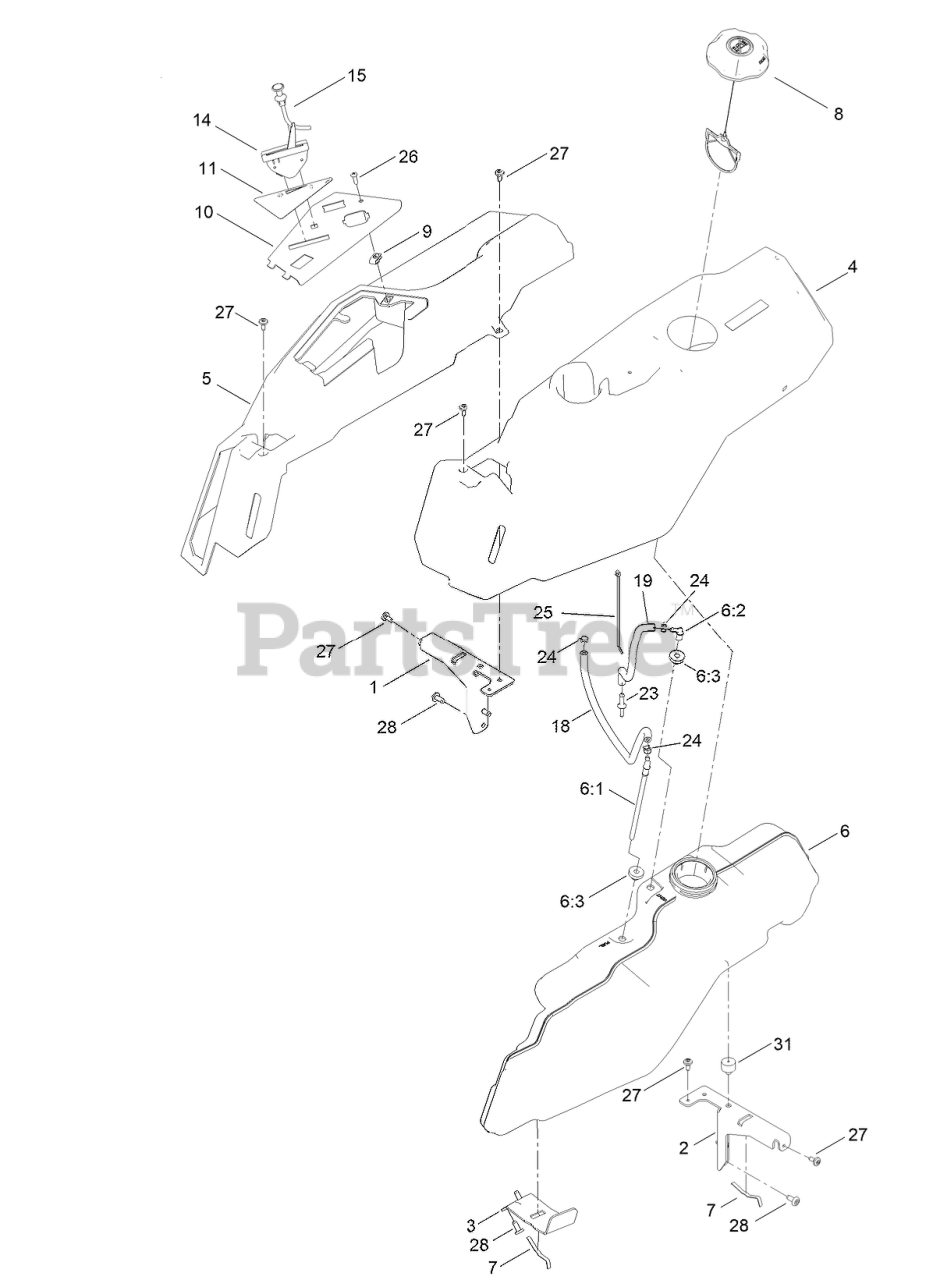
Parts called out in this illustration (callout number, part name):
1	SUPPORT-POD, RH
2	SUPPORT-POD, LH
3	SUPPORT-TANK, FUEL
4	POD-LH
5	POD-RH
6	FUEL TANK ASM
6:1	CONNECTOR-ELBOW, 90 DEG
6:2	FITTING-PLASTIC
6:3	BUSHING
7	SPRING
8	CAP-FUEL, RATCHETING
10	PANEL - CONTROL
11	DECAL-PANEL, CONTROL
14	CABLE-THROTTLE
15	CABLE-CHOKE
18	HOSE-FUEL
19	HOSE-FUEL
23	ADAPTOR-ORIFICE
24	CLAMP-HOSE
25	TIE-CABLE
26	SCREW-PRH
27	SCREW-SHOULDER
31	BUMPER-GROMMET
